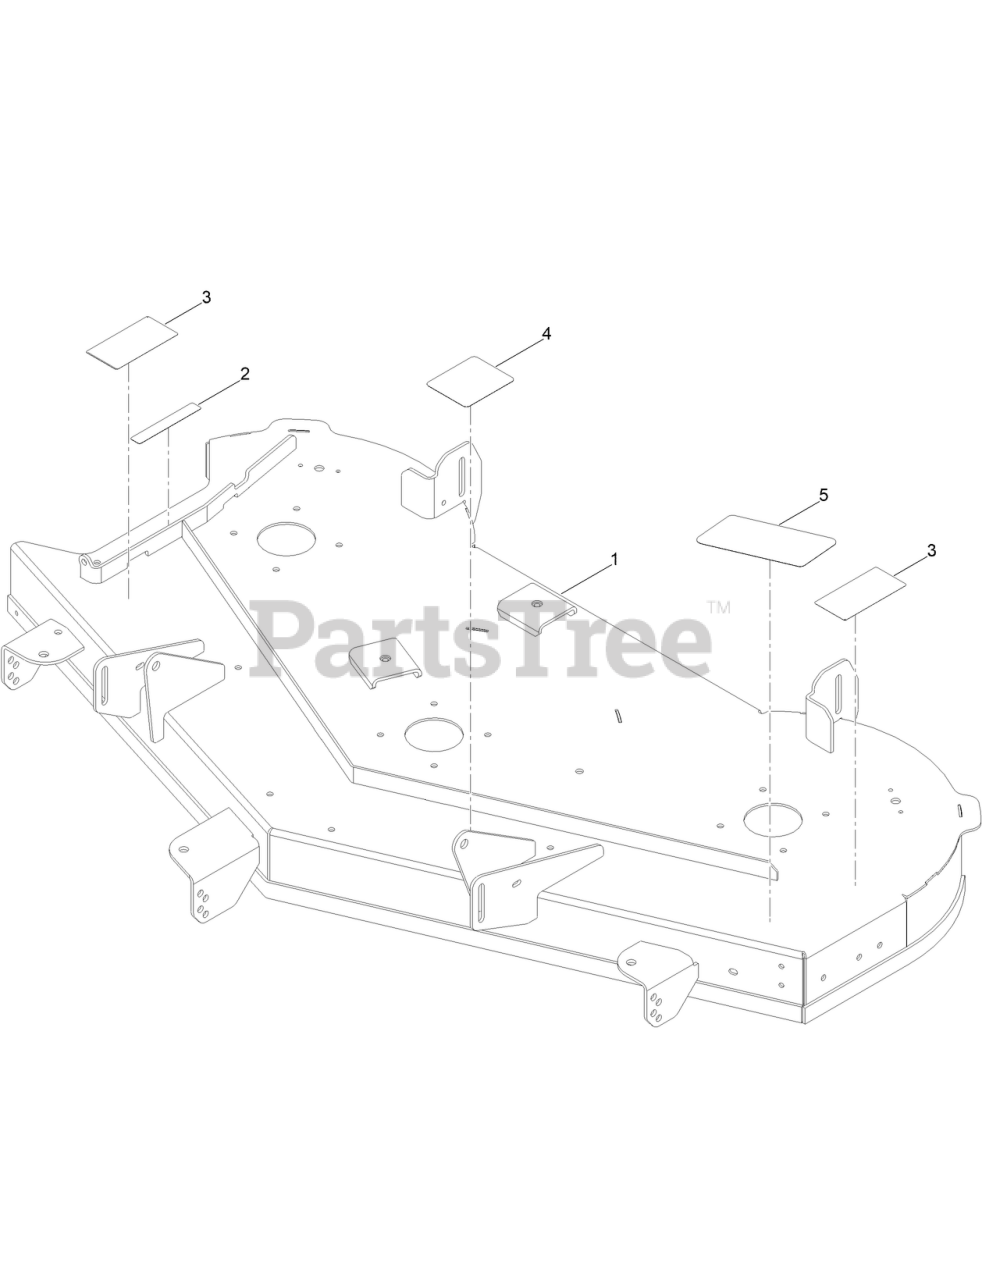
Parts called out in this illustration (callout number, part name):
2	DECAL-DANGER
3	DECAL-DANGER, DECK
4	DECAL-BELT ROUTING 54in
5	DECAL-DECK 54in
